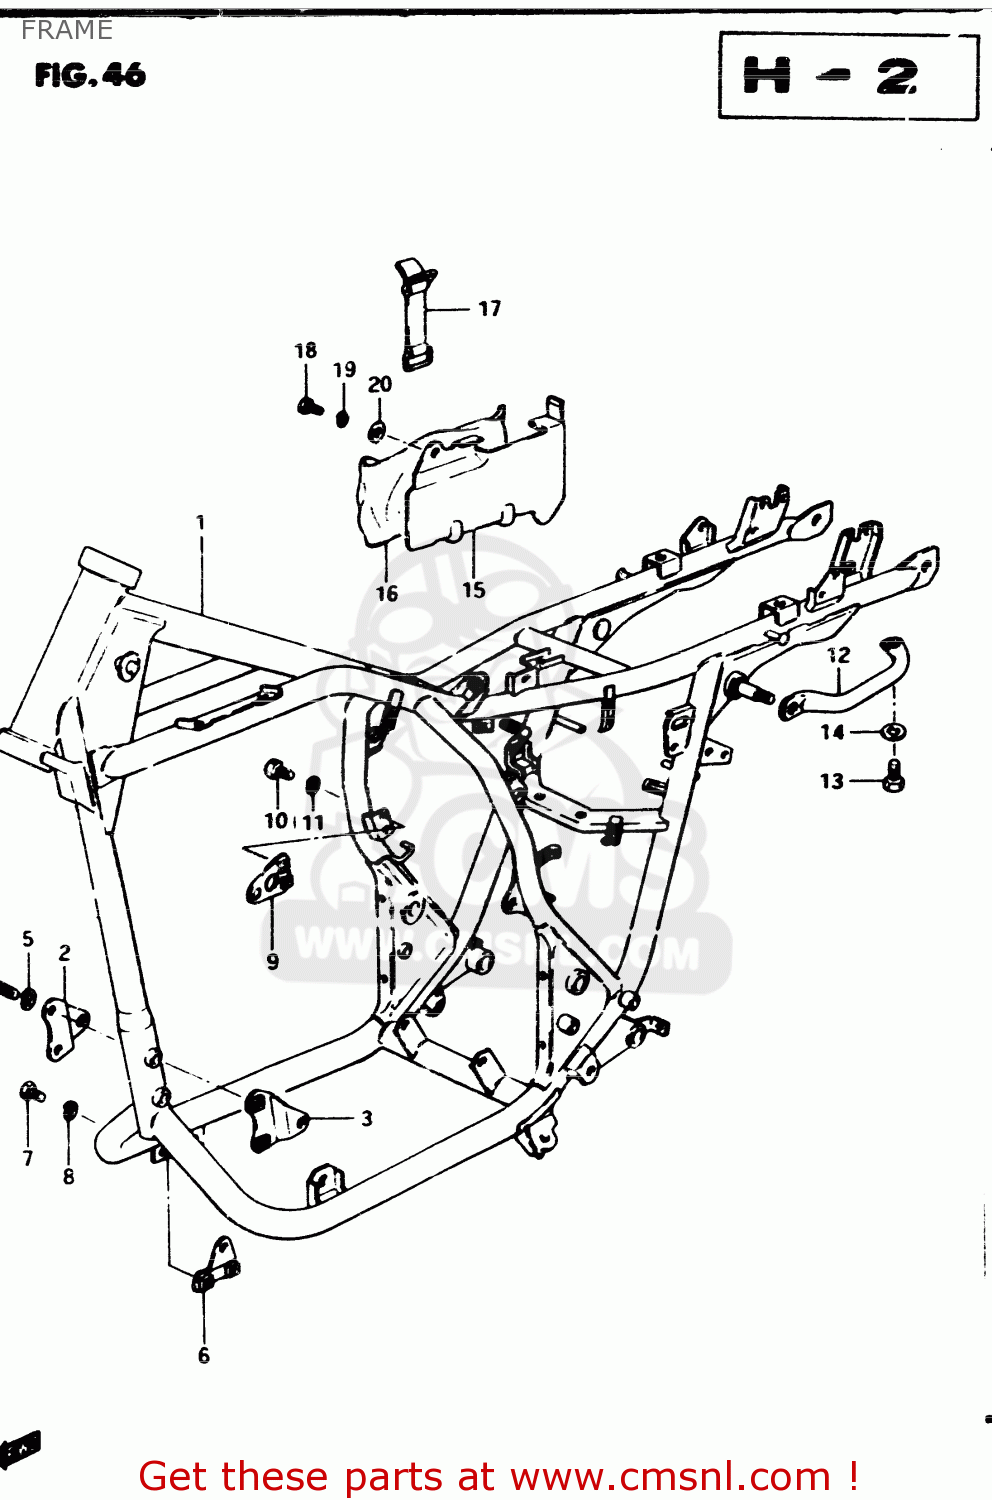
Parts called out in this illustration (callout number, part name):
1	FRAME (BLACK)
2	PLATE,MOUNTING NO.1,RIGHT
3	PLATE,ENGINE MOUNTING
4	BOLT
5	LOCK WASHER
6	PLATE,MOUNTING NO.2,LEFT
7	BOLT
8	LOCK WASHER
9	PLATE,MOUNTING NO.4,LEFT
10	BOLT
11	LOCK WASHER
12	GRIP,FRAME HANDLE
13	BOLT
14	WASHER
15	HOLDER,TOOL
16	TOOL SET
17	BAND
18	BOLT
19	LOCK WASHER
20	WASHER
